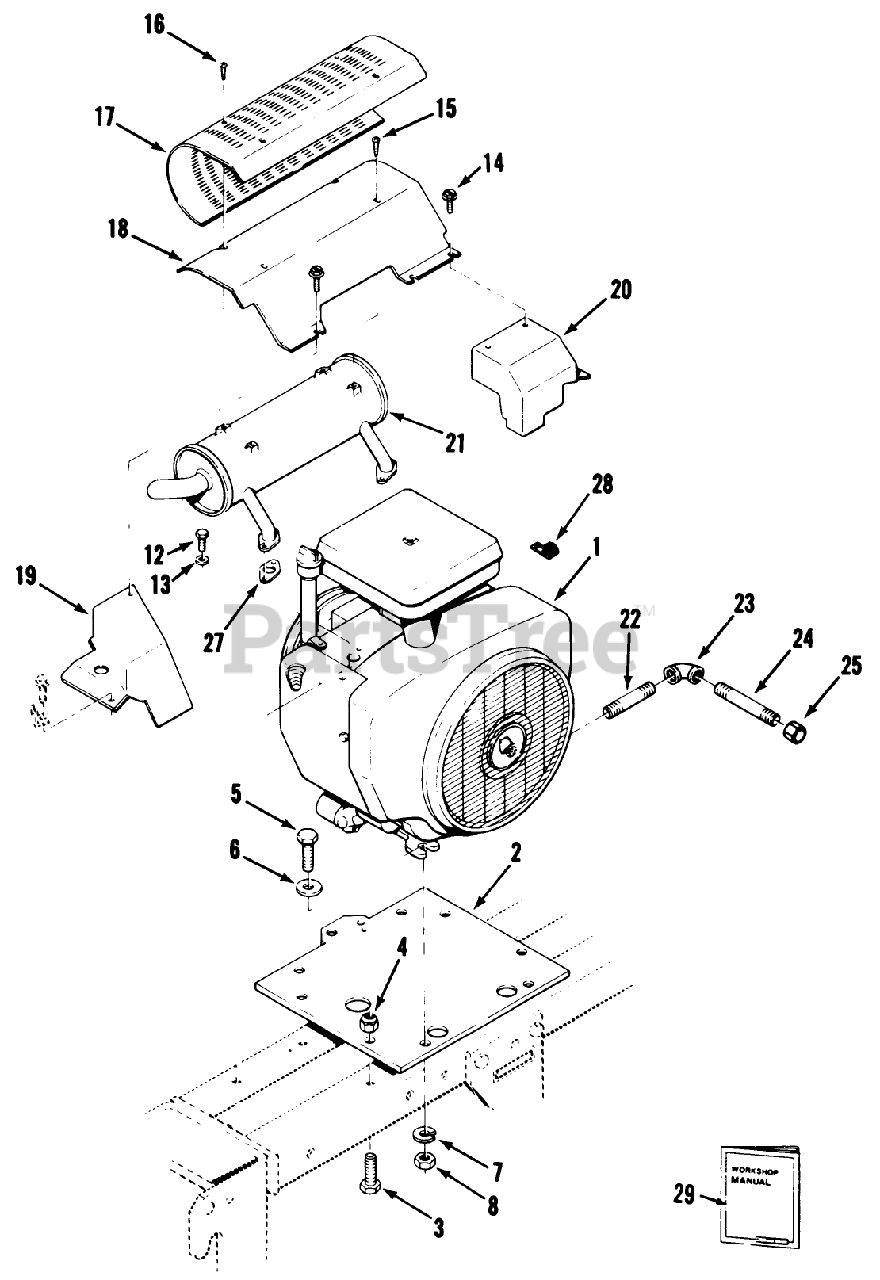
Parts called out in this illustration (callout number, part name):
2	PLATE-ENGINE *B
3	SCREW-HH
4	NUT-LOCK, NI
5	SCREW-HH
6	WASHER-FLAT
12	SCREW-HH
13	WASHER-LOCK
17	SHIELD
21	MUFFLER-EXHAUST
23	ELBOW 3/8 90 DEG
24	PIPE-NIPPLE 3/8 X 4"
28	CLIP
29	Manual-Toro Power Plus Service
